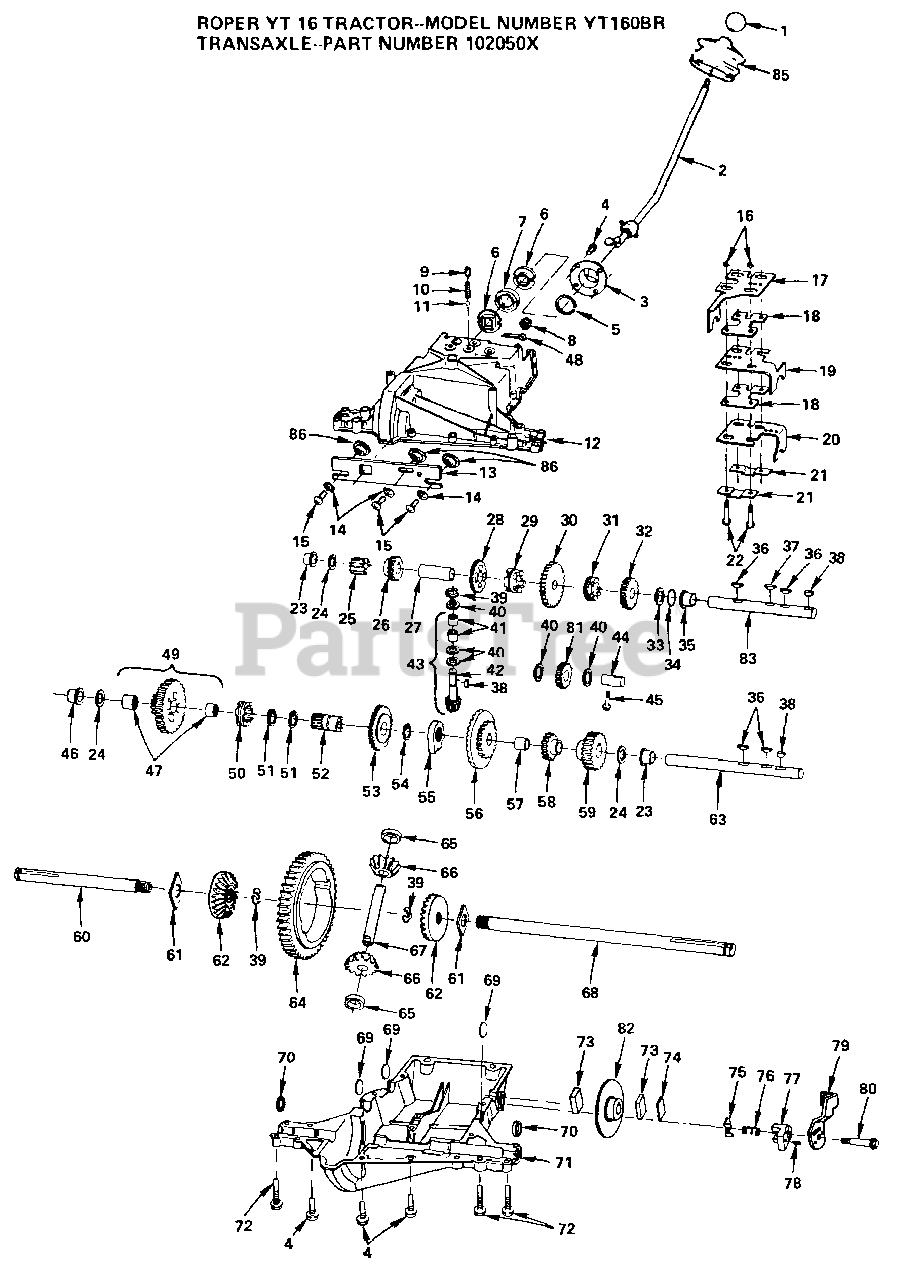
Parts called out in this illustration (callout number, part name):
4	SCREW HEX CRT
5	SPRING - WAVE
6	SOCKET - LEVER, SHIFT
7	INSERT-SHIFT YT
15	SCREW.HXHD.10-2
17	FORK - SHIFT, PRIMARY
18	PLT-SEPARATOR L
20	FORK-SHIFT YTV
25	GEAR-SPUR 13T Y
28	GEAR - SPUR, 27T
30	GEAR - SPUR, 37T
39	KLIP RING
40	"T, BEARING"
44	SHAFT - IDLER, REVERSE
45	SCREW YTV
49	GEAR ASSY YTV
63	SHAFT PRIMARY Y
72	SCREW YTV
73	PAD-BRAKE YTV
74	SHIM - BRAKE, HARDENED
75	PLATE, BEARING
77	CALIPER - BRAKE
80	BOLT - SHOULDER
82	DISC-BRAKE YTV
84	LUBRICANT YTV
